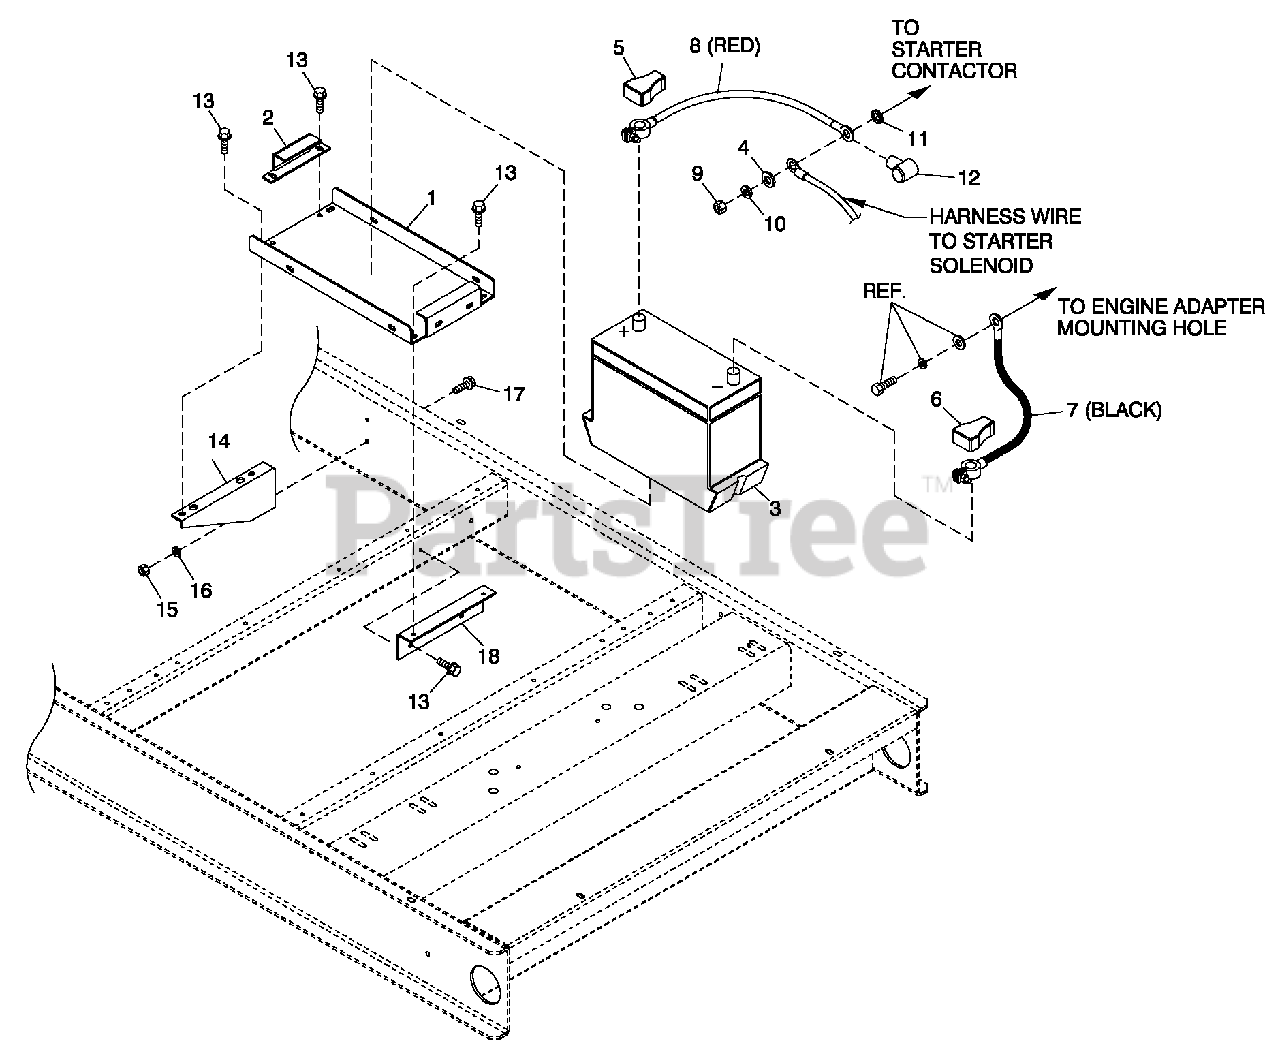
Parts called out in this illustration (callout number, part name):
1	TRAY BATTERY 27F
2	STRAP BATTERY RETAINMENT 27F
3	BATTERY 12VDC 90-AH 27F
4	WASHER FLAT 3/8-M10 ZINC
5	BATTERY POST COVER RED +
6	BATTERY POST COVER BLK -
7	CABLE BATTERY BACLK #1 X 26.00
8	CABLE BATTERY RED #1 X 28.00
9	NUTHEXM8-1.25 G8YEL CHR
10	WASHER LOCK M8-5/16
11	WASHER SHAKEPROOF EXT 5/16 STL
12	BOOT BATTERY CABLE
13	SCREW THF M6-1 X 16 N WA Z/JS
14	SUPPORT BATTERY TRAY
15	WASHER LOCK M6-1/4
16	NUT HEX M6X 1.0 G8YEL CHR
17	SCREW HHC M6-1.0X 20 G8.8
18	SUPPORT 27F BATTERY
